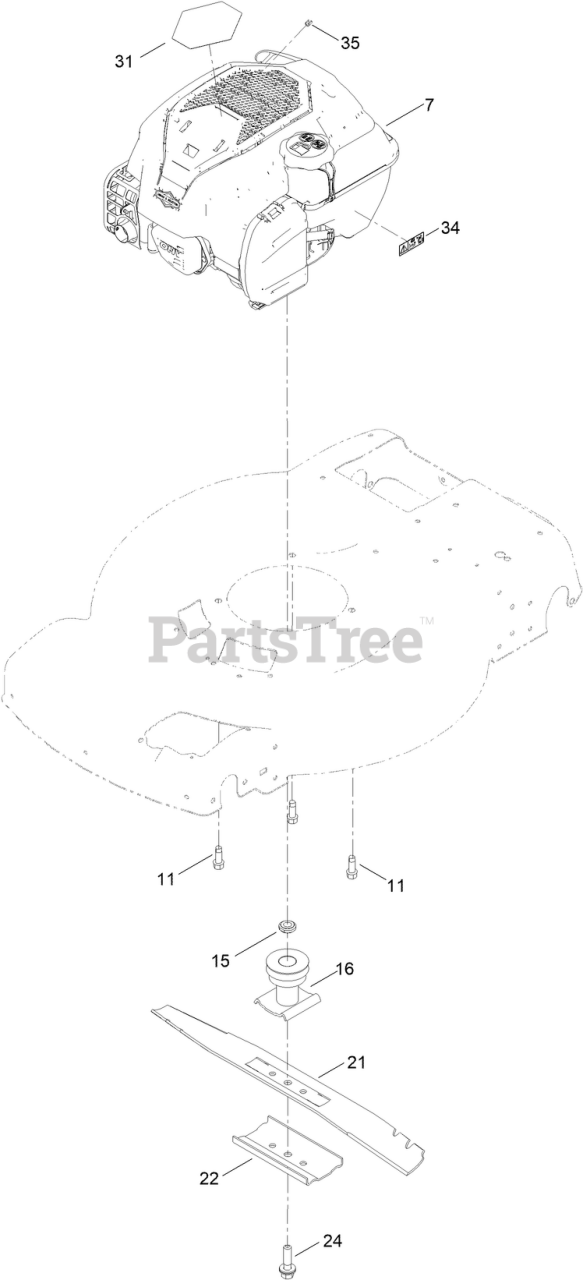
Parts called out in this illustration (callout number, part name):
11	SCREW-THD FORM, HWH
15	SPACER-DRIVER
16	DRIVER-BLADE
22	SUPPORT-BLADE
24	BOLT-BLADE
31	DECAL-SHROUD
34	DECAL-LEVEL, FUEL
35	STOP-ROPE
